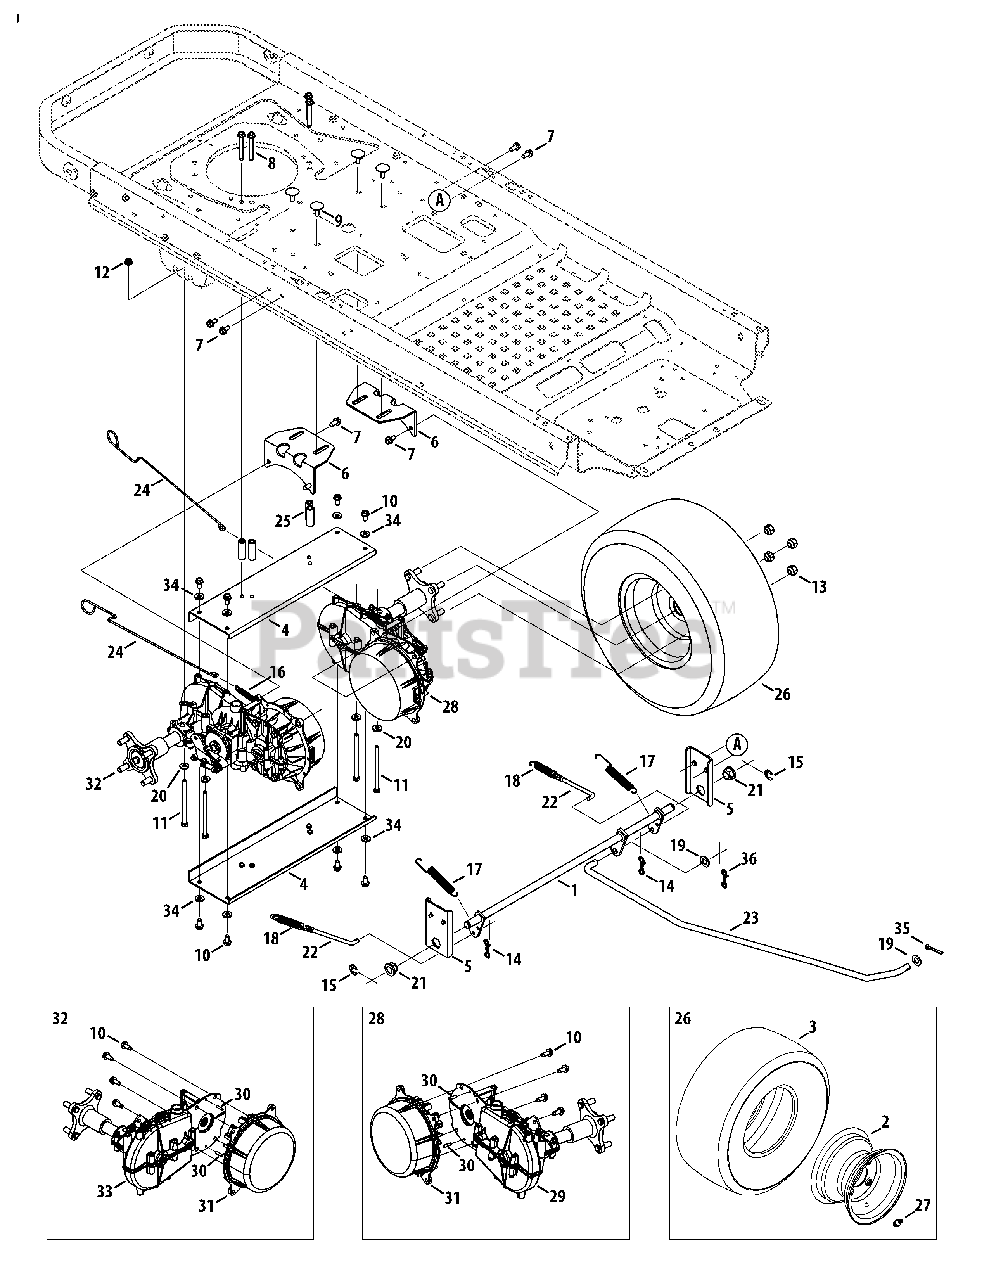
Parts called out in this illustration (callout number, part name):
1	Shift Assembly
3	Tire Only, 18 x 8.5-8
4	Axle Support Bracket
5	Shift Assembly Mounting Bracket
6	Transmission Mounting Bracket
7	Hex Washer Screw, 5/16-18 x .750
8	Hex Washer Screw, 5/16-18 x 2.50
9	Screw, 5/16-18 x 1.00
10	Hex Washer Head Screw, 5/16-18 x .75
11	Hex Cap Screw 5/16-18 x 4.50
12	Flange Lock Nut, 5/16-18
13	Lug Nut, 7/16-14
14	Bow-Tie Cotter Pin
15	E-Ring, .625
16	Extension Spring, .429OD x 2.515
17	Extension Spring, .63 DIA x 4.95 LG
18	Extension Spring, .59 OD x 4.00 LG
19	Flat Washer, .510 x 1.00 x .060
20	Flat Washer, .344 x .750 x .120
21	Hex Flange Bearing
25	Spacer, .345 x .625 x 1.798
26	Complete Wheel, 18 x 8.5-8 (42" & 46)
27	Valve Tubeless
28	Transmission Assembly, Whl Mtr, RH
29	Tranmission Assembly, RH
30	Dowel Pin, 3/16 x 3/4
31	Electric Motor, 48V
32	Transmission Assembly, Whl Mtr, LH
33	Tranmission Assembly, LH
34	Flat Washer, .344 x .688 x .065
35	Cotter Pin, 5/32 x 1.25
36	Bow-Tie Cotter Pin
